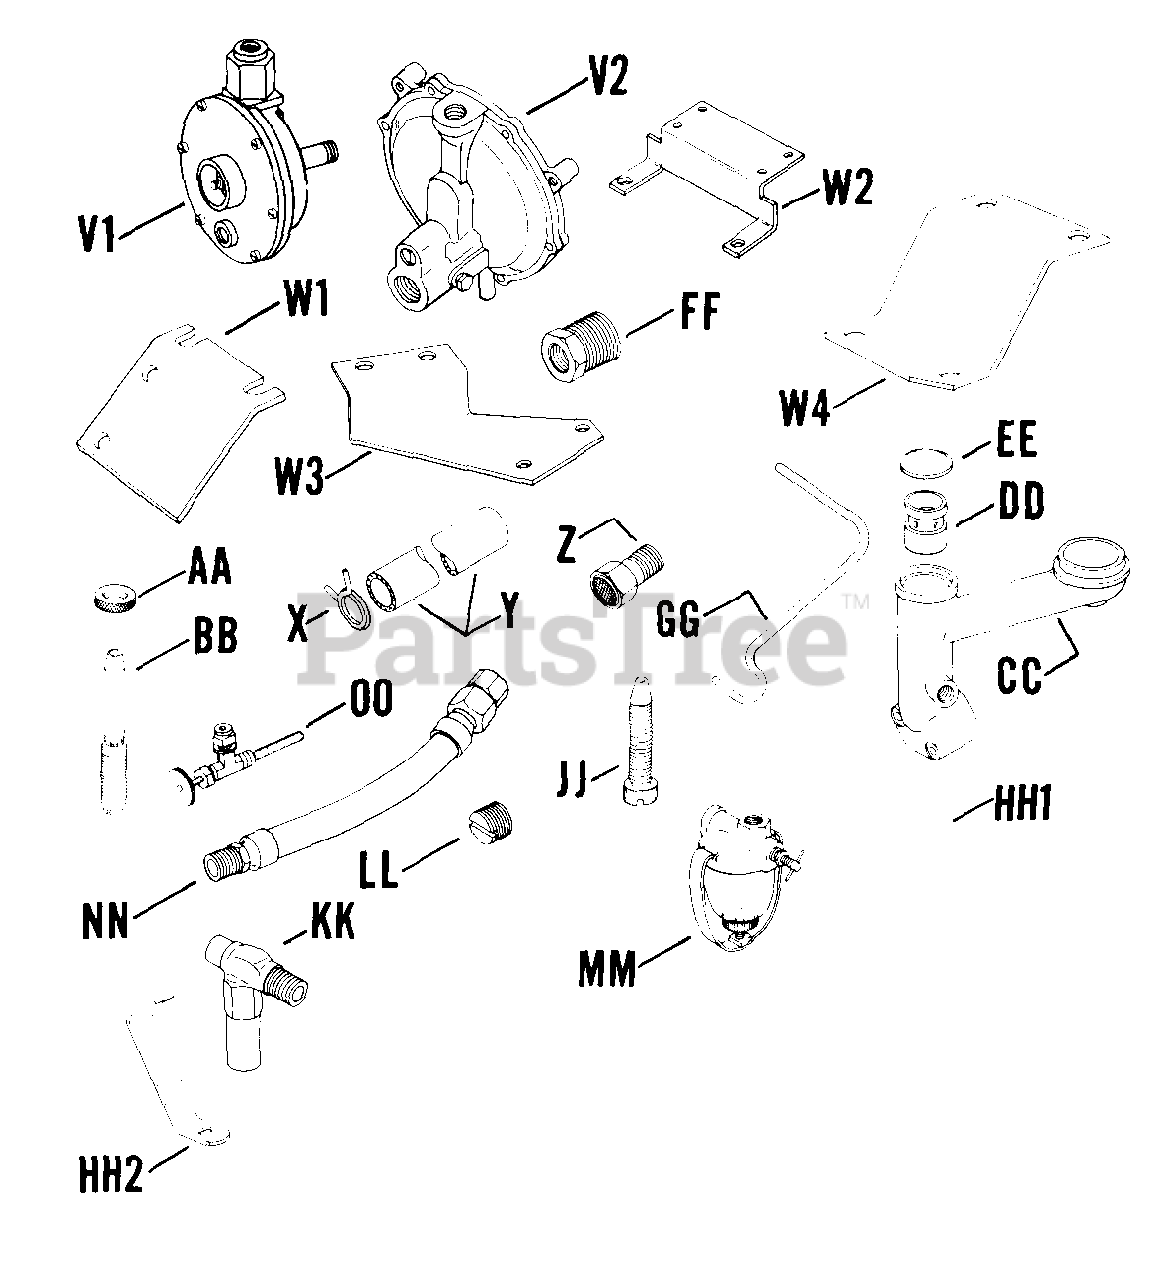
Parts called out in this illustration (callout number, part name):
V1	REGULATOR - DISCONTINUED
X	USE X-426-3
Y	HOSE - USE X-422-5
